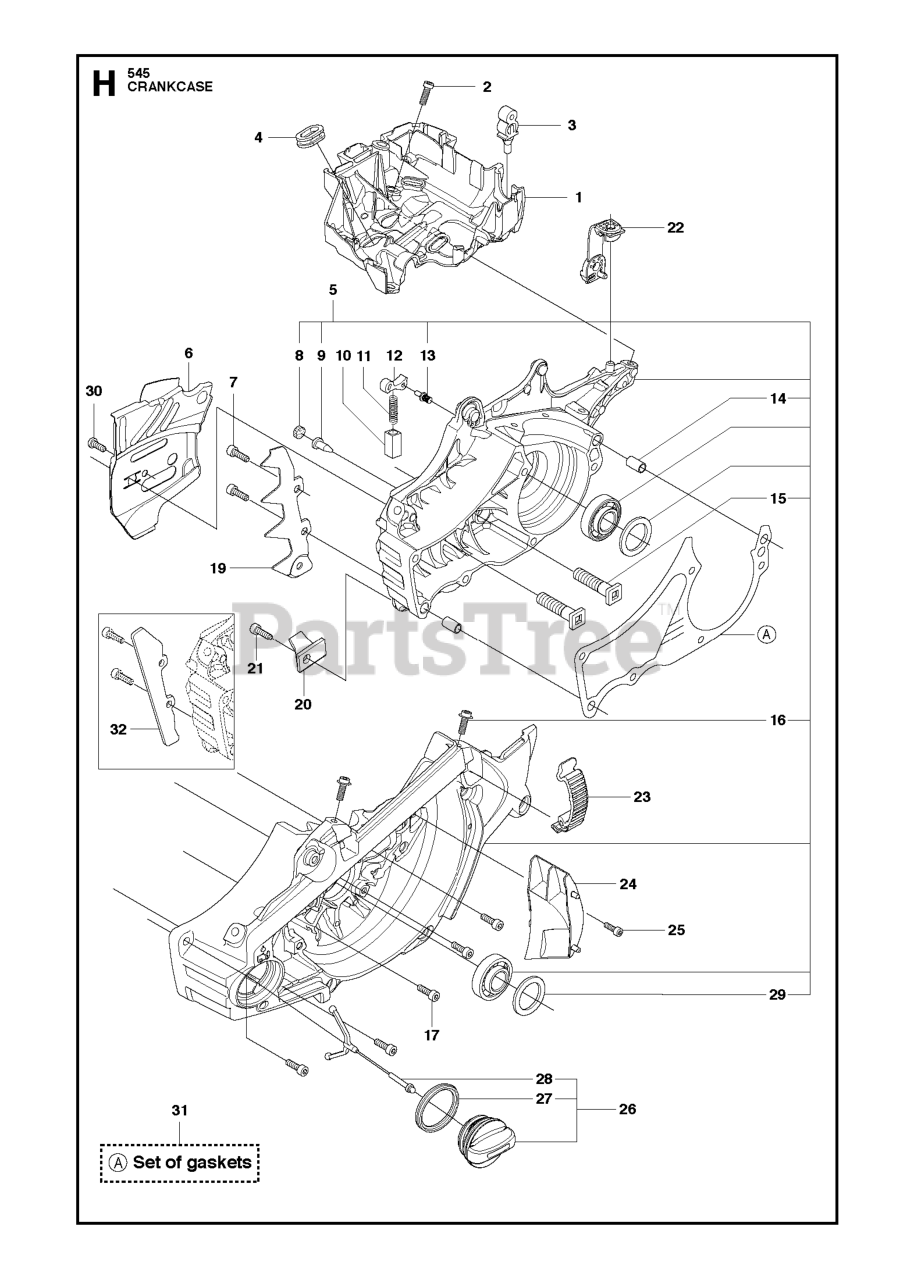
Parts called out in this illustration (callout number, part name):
1	CARBURETTOR AREA BASE
3	SUPPORT
5	CRANKCASE ASSY
6	CHAIN GUIDE PLATE
8	PLUG
9	VALVE-CHECK (DUCKBILL)
11	LOCK SPRING
13	PIN
14	SLEEVE
15	BAR BOLT
16	SCREW IHSCM
17	SCREW MC6S 5X25
20	CHAIN CATCHER
22	DEFLECTION LIMITER
23	BUCKLE ORANGE
24	AIR NOZZLE
25	SCREW IHSCM
26	RP TANK CAP ASSY
27	SEALING
28	TANK LOCK
29	RADIAL SEAL
31	GASKET KIT
32	BUMPER, BAG
